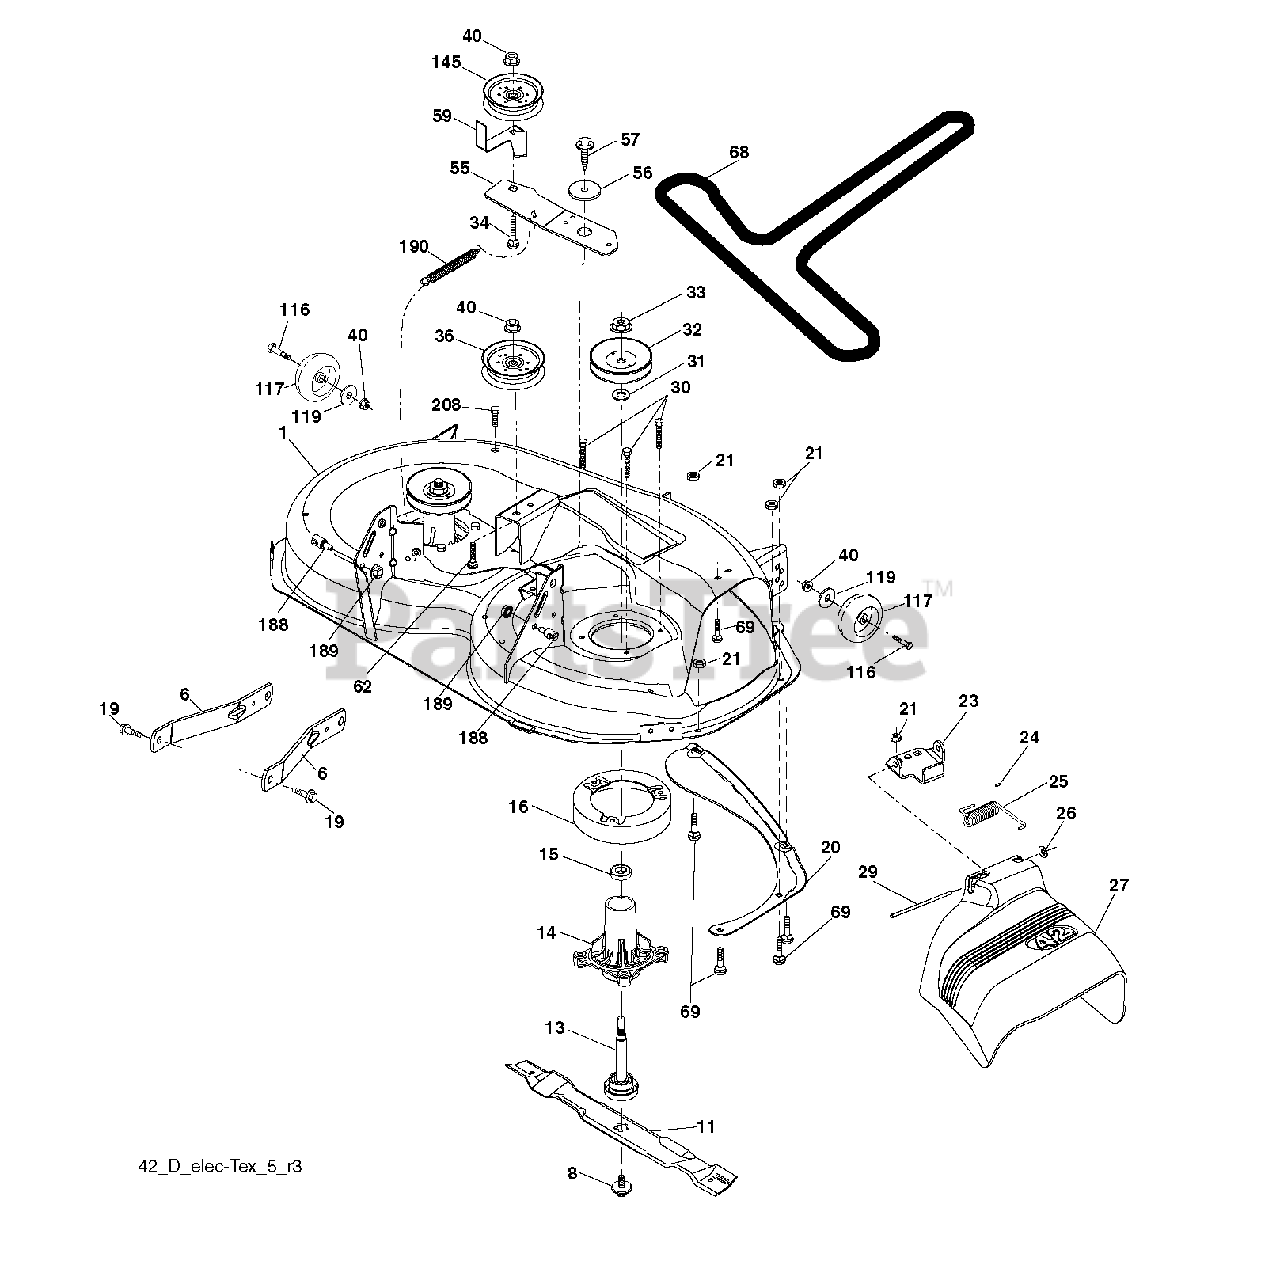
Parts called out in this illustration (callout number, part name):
1	DECK.WELDMENT.42"
6	ARM.SUSPENSION.MOWER.R
8	BOLT.WASHER.ASM.7/16-2
11	42" HI-LIFT BLADE
13	SHAFT.ASM.MDRL.N/GREASE.38
14	HOUSING MANDREL
16	STRIPPER, MWR ROUND
19	BOLT.SHOULDER
20	BAFFLE.VORTEX
21	LOCKNUT
23	BRKT.DEFLECTOR.38"2005+
24	CAP-SLEEVE LT
25	SPRING.TORSION.DEFLECT
26	NUT PUSH M
27	SHIELD.DEFLECTOR.MOWER.42"BLAC
29	ROD.HINGE
30	SCREW, WASHER HEAD
31	WASHER.SPACER.MANDREL
32	PULLEY/MANDREL
33	NUT.FLANGE.LOCK.TOP
34	BOLT.3/8-16X1.50
36	PULLEY.IDLER.2006
40	NUT LOCK FLG 3/8-16 UNC
55	IDLER.ARM
56	SPACER.RETAINER
57	SCREW 3/8-16X1
59	GUARD, BELT
62	BOLT
68	BELT V SECONDARY
69	BOLT
117	WHEEL.GAGE.HALF.SPOKED
118	LOCKNUT
119	WASHER
145	PULLEY.IDLER.48"PRIMARY
188	STUD.FASTNER.W/ANTI-ROTATE
189	NUT LOCK HEX FLANGE 5/16-18
190	SPRING.MOWER.DRIVE.ELECTRIC
208	SCREW 3/8-16X1/2
